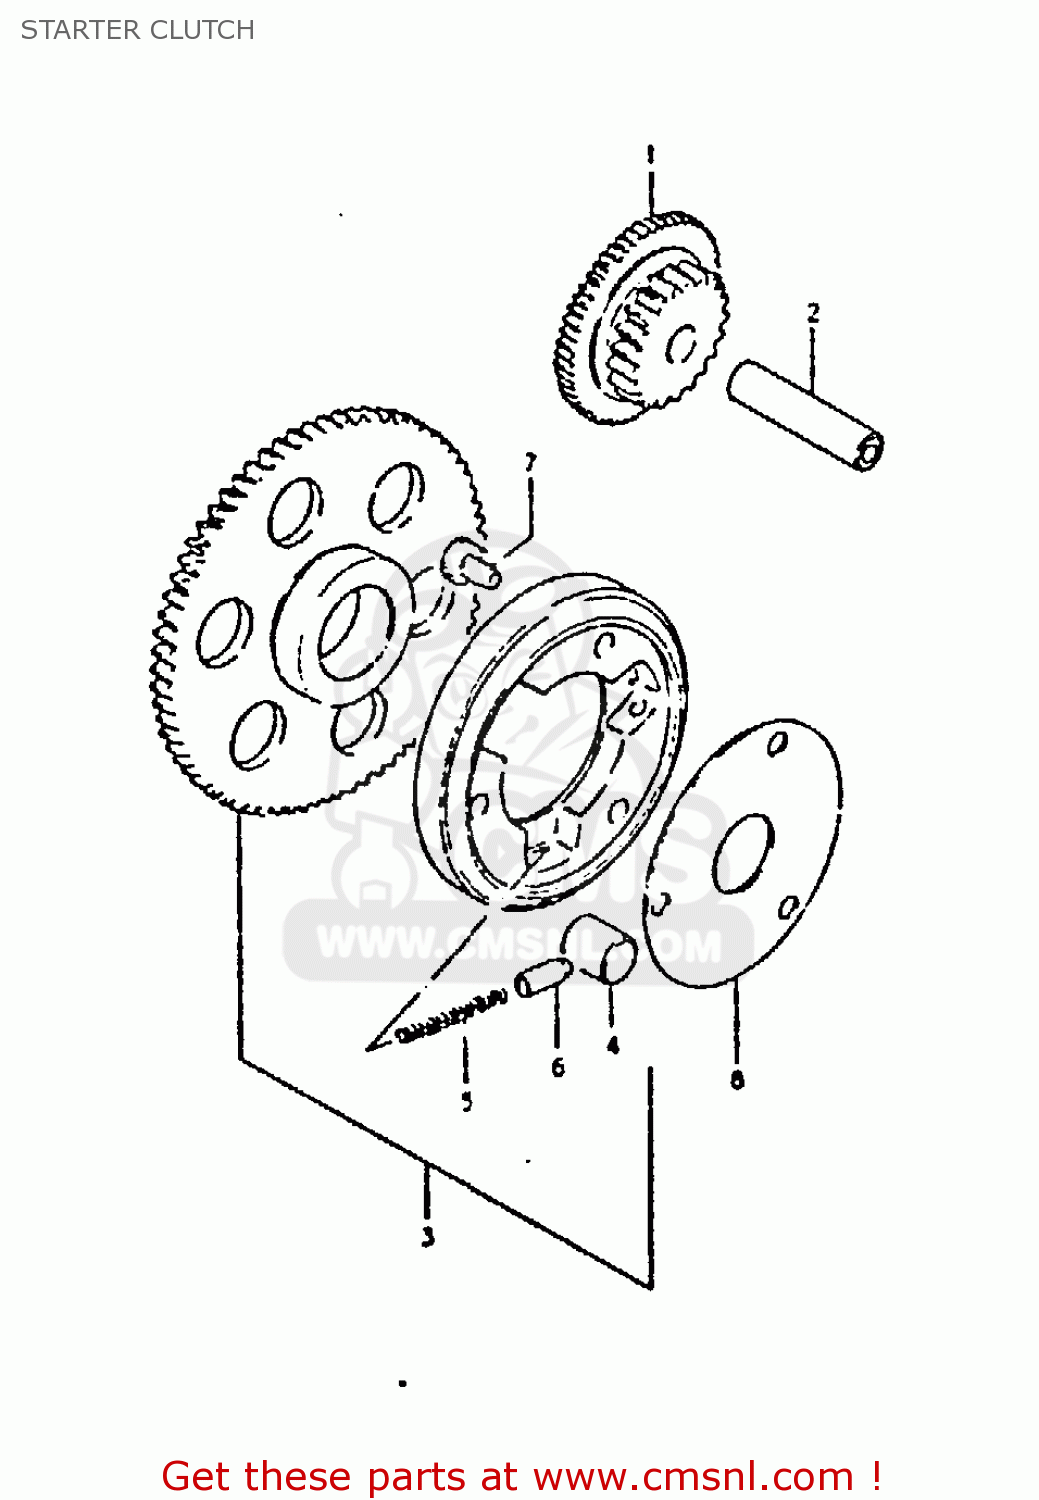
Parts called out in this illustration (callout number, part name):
1	GEAR,STARTER IDLE
2	PIN(7.4X13X40)
3	CLUTCH SET,STARTER
4	ROLLER(15X13)
5	SPRING
6	PIECE,PUSH
7	BOLT
8	SHIM,STARTER CLUTCH HUB
